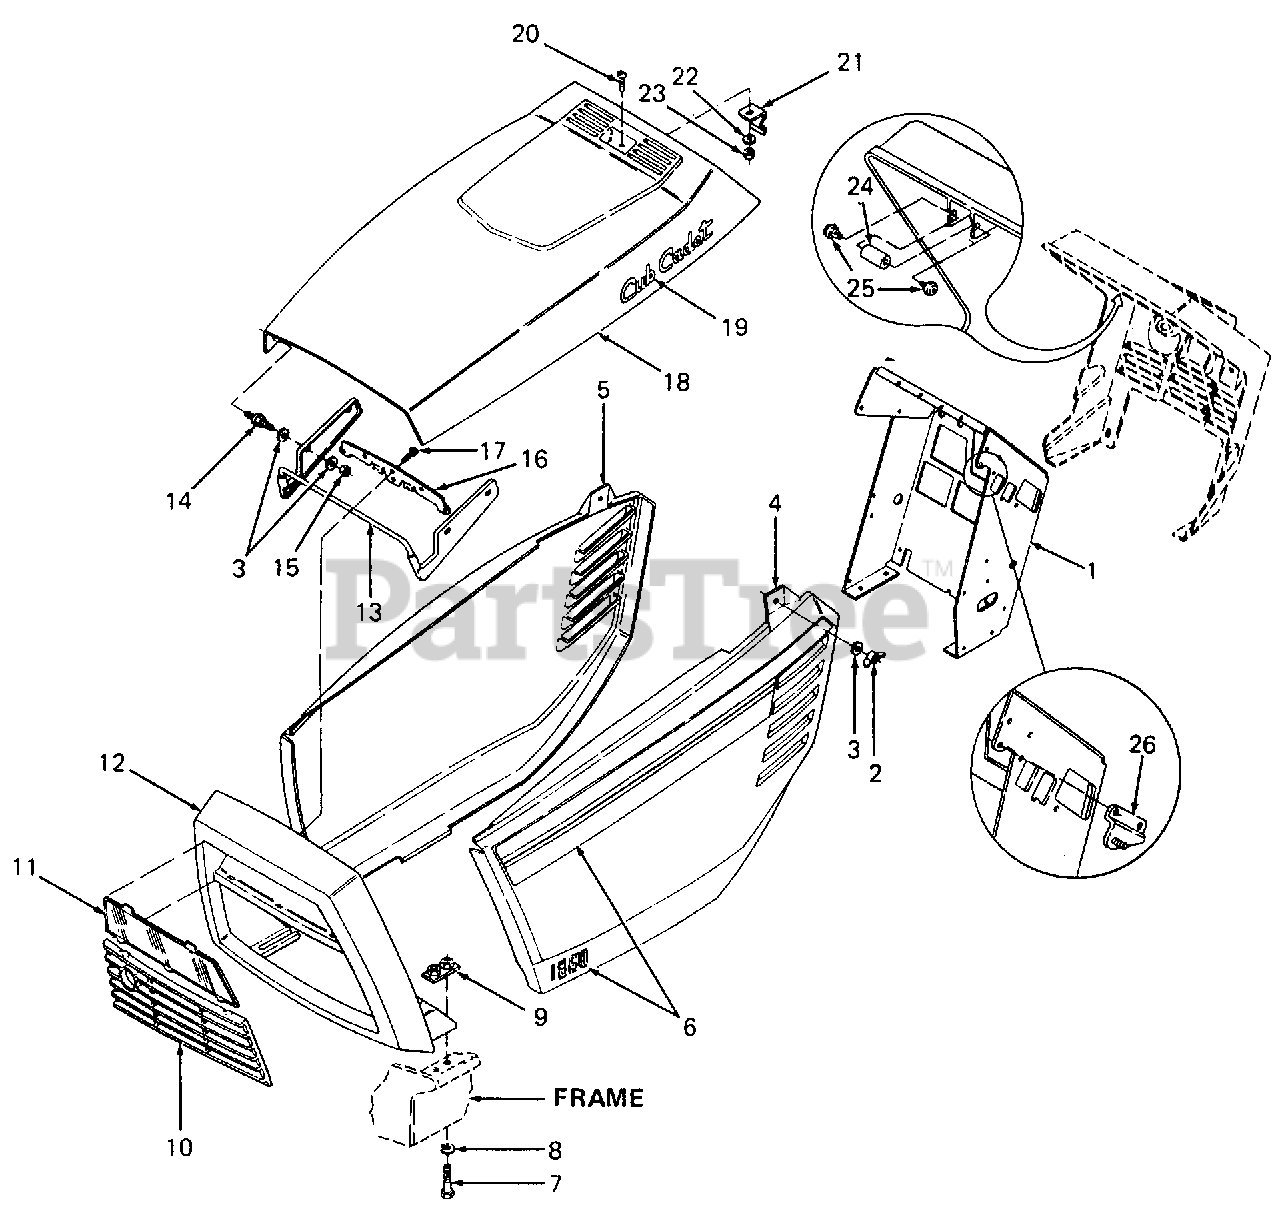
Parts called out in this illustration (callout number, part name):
3	Washer, Flat, .251 X .62 X .052 Thk
4	Panel, LH Side
5	Panel, RH Side
6	Graphics Kit, LH Side Panel
7	Screw, Hex Cap, 5/16-18 X 1.0 Lg GR5
8	Washer, Lock, 5/16
9	Retainer, Grille Housing
10	Grille, Insert
11	Grille, Lens
12	Grille w/Label
15	Nut, Hex Patch Lock, 1/4-20
18	Hood
19	Graphic, Cub Cadet Script w/Studs
20	Screw, Truss Hd, #8-32 X .38 Lg
21	Clip, Hood Latch
22	Washer, Flat, .16 X .38 X .045 Thk
23	Nut, Hex Keps, #8-32
24	Pin, Latch
25	Screw, Phillips Hd Truss Mach, 1/4-20 X .50 Lg
